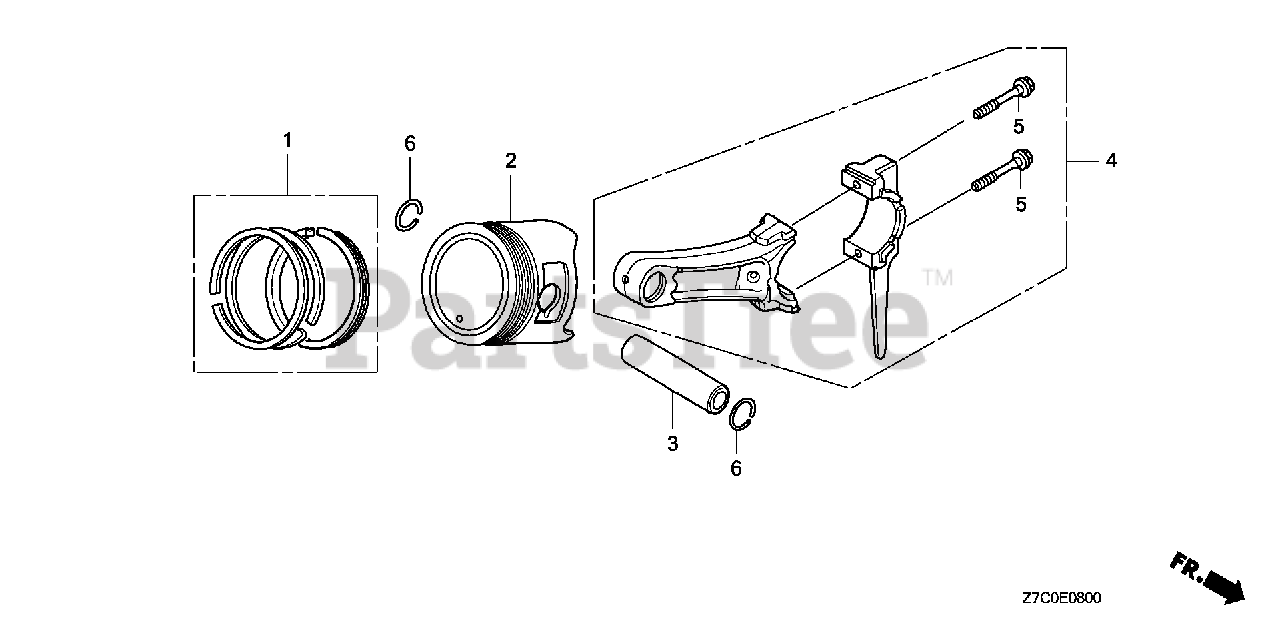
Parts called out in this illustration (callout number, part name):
1	RING SET, PISTON (STD) (TPR)
1	RING SET, PISTON (0.25) (TPR)
1	RING SET, PISTON (0.50) (TPR)
1	RING SET, PISTON (0.75) (TPR)
2	PISTON (STD)
2	PISTON (0.25)
2	PISTON (0.50)
2	PISTON (0.75)
3	PIN, PISTON
4	ROD ASSY., CONNECTING (0.25 LOWER SIZE)
4	ROD ASSY., CONNECTING (STD)
5	BOLT, CONNECTING ROD
6	CLIP, PISTON PIN (18MM)
